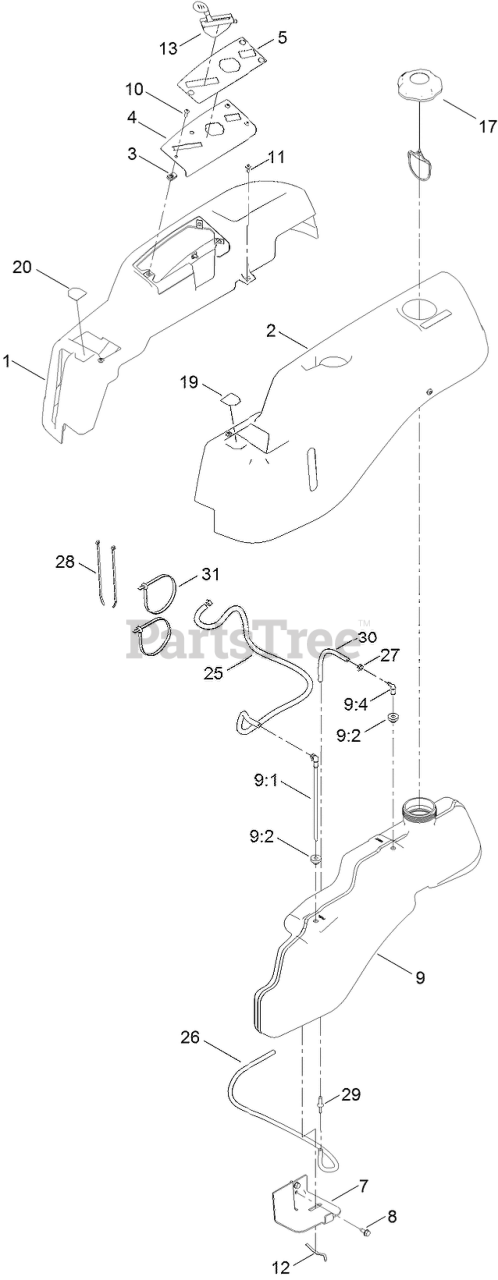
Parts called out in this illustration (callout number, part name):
1	POD-RH
2	POD-LH
4	PLATE-CONTROL
5	DECAL-PANEL, CONTROL
7	SUPPORT-TANK, FRONT
8	SCREW-HWHTF
9	FUEL TANK ASM
9:1	CONNECTOR-ELBOW, 90 DEG
9:2	BUSHING
9:4	FITTING-PLASTIC
10	SCREW-PRH
11	SCREW-SHOULDER
12	SPRING
13	CABLE-THROTTLE AND CHOKE
17	CAP-FUEL, RATCHETING
19	DECAL-LEVER, CONTROL (LH)
20	DECAL-LEVER, CONTROL (RH)
25	HOSE-FUEL
26	HOSE-FUEL
27	CLAMP-HOSE
28	TIE-CABLE
29	ADAPTOR-ORIFICE
30	HOSE-FUEL
31	TIE-CABLE
